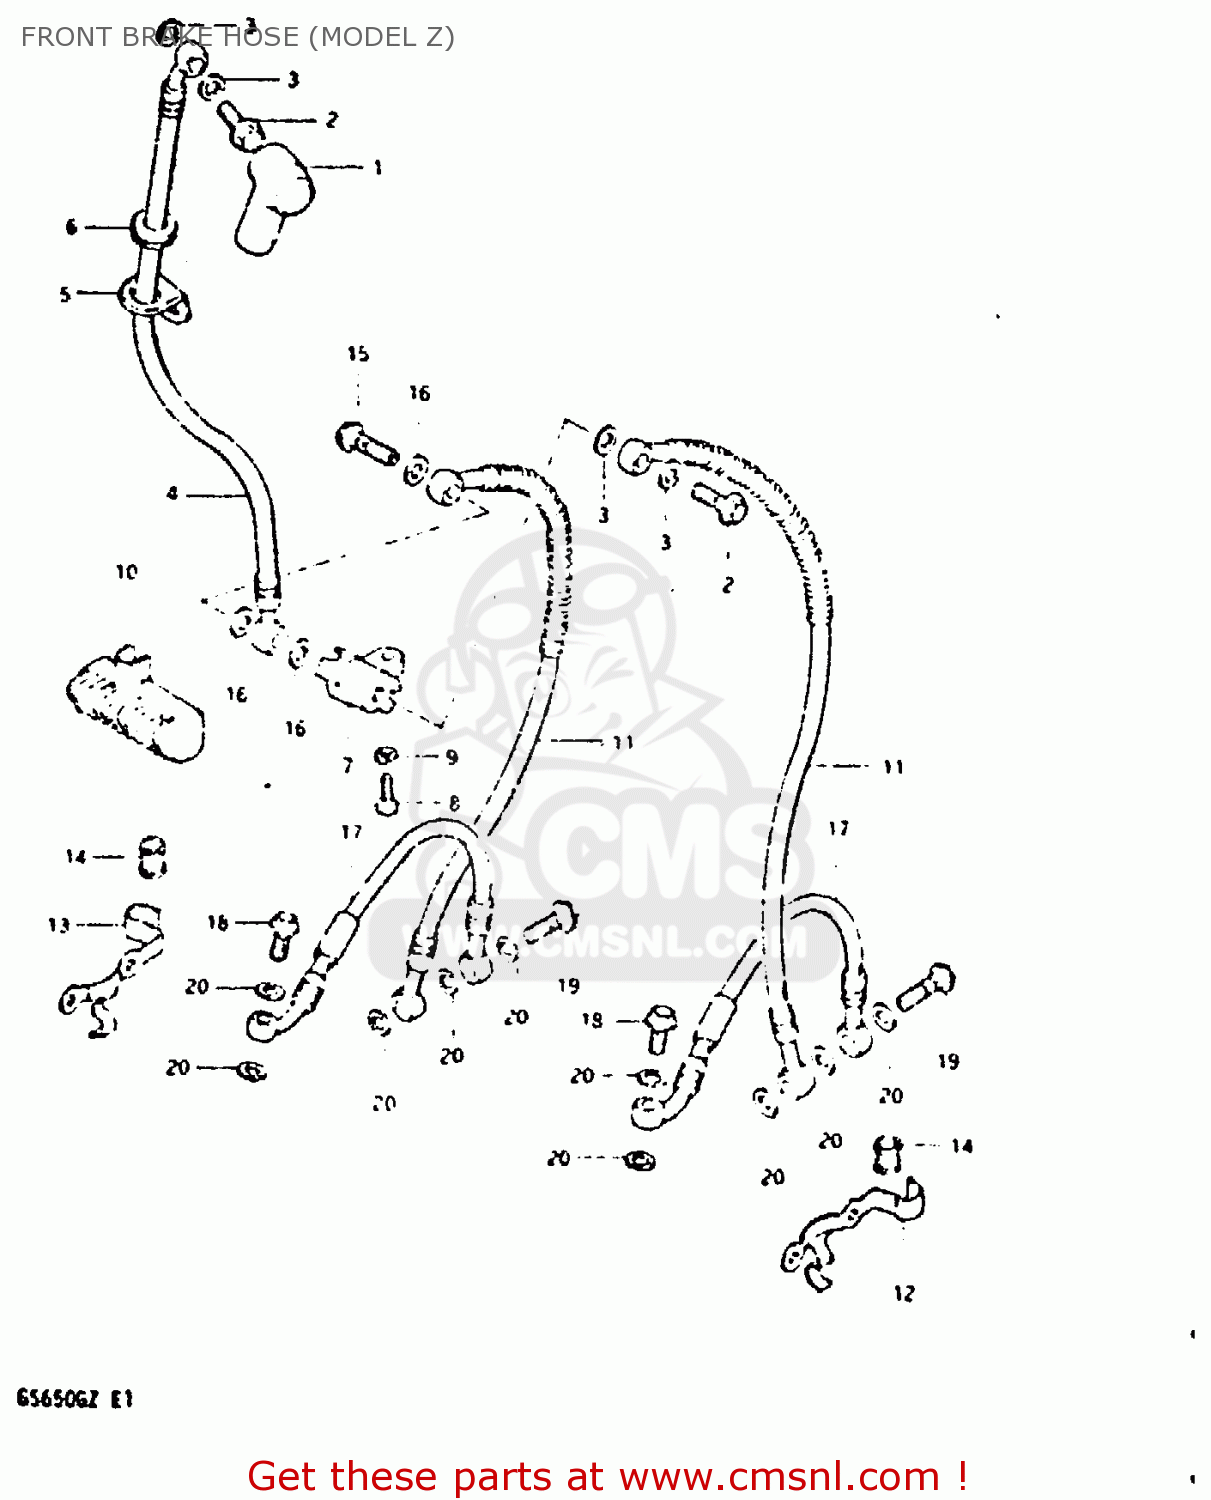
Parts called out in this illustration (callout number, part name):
1	BOOT,MASTER CYLINDER
2	BOLT,UNION
3	WASHER
4	HOSE, BRAKE NO.1 (FOR NEUTRAL HANDLEBAR)
5	GUIDE,BRAKE HOSE NO.1
6	GROMMET
7	JOINT,BRAKE HOSE
8	BOLT
9	LOCK WASHER
10	COVER,BRAKE HOSE JOINT
11	HOSE,FRONT BRAKE
12	CLAMP,FRONT BRAKE HOSE
13	CLAMP,FRONT BRAKE HOSE
14	BUSH,BRAKE HOSE GUIDE,NO.2
15	BOLT,UNION
16	WASHER
17	HOSE,ANTI NOSE
18	BOLT,UNION
19	BOLT,UNION
20	WASHER
